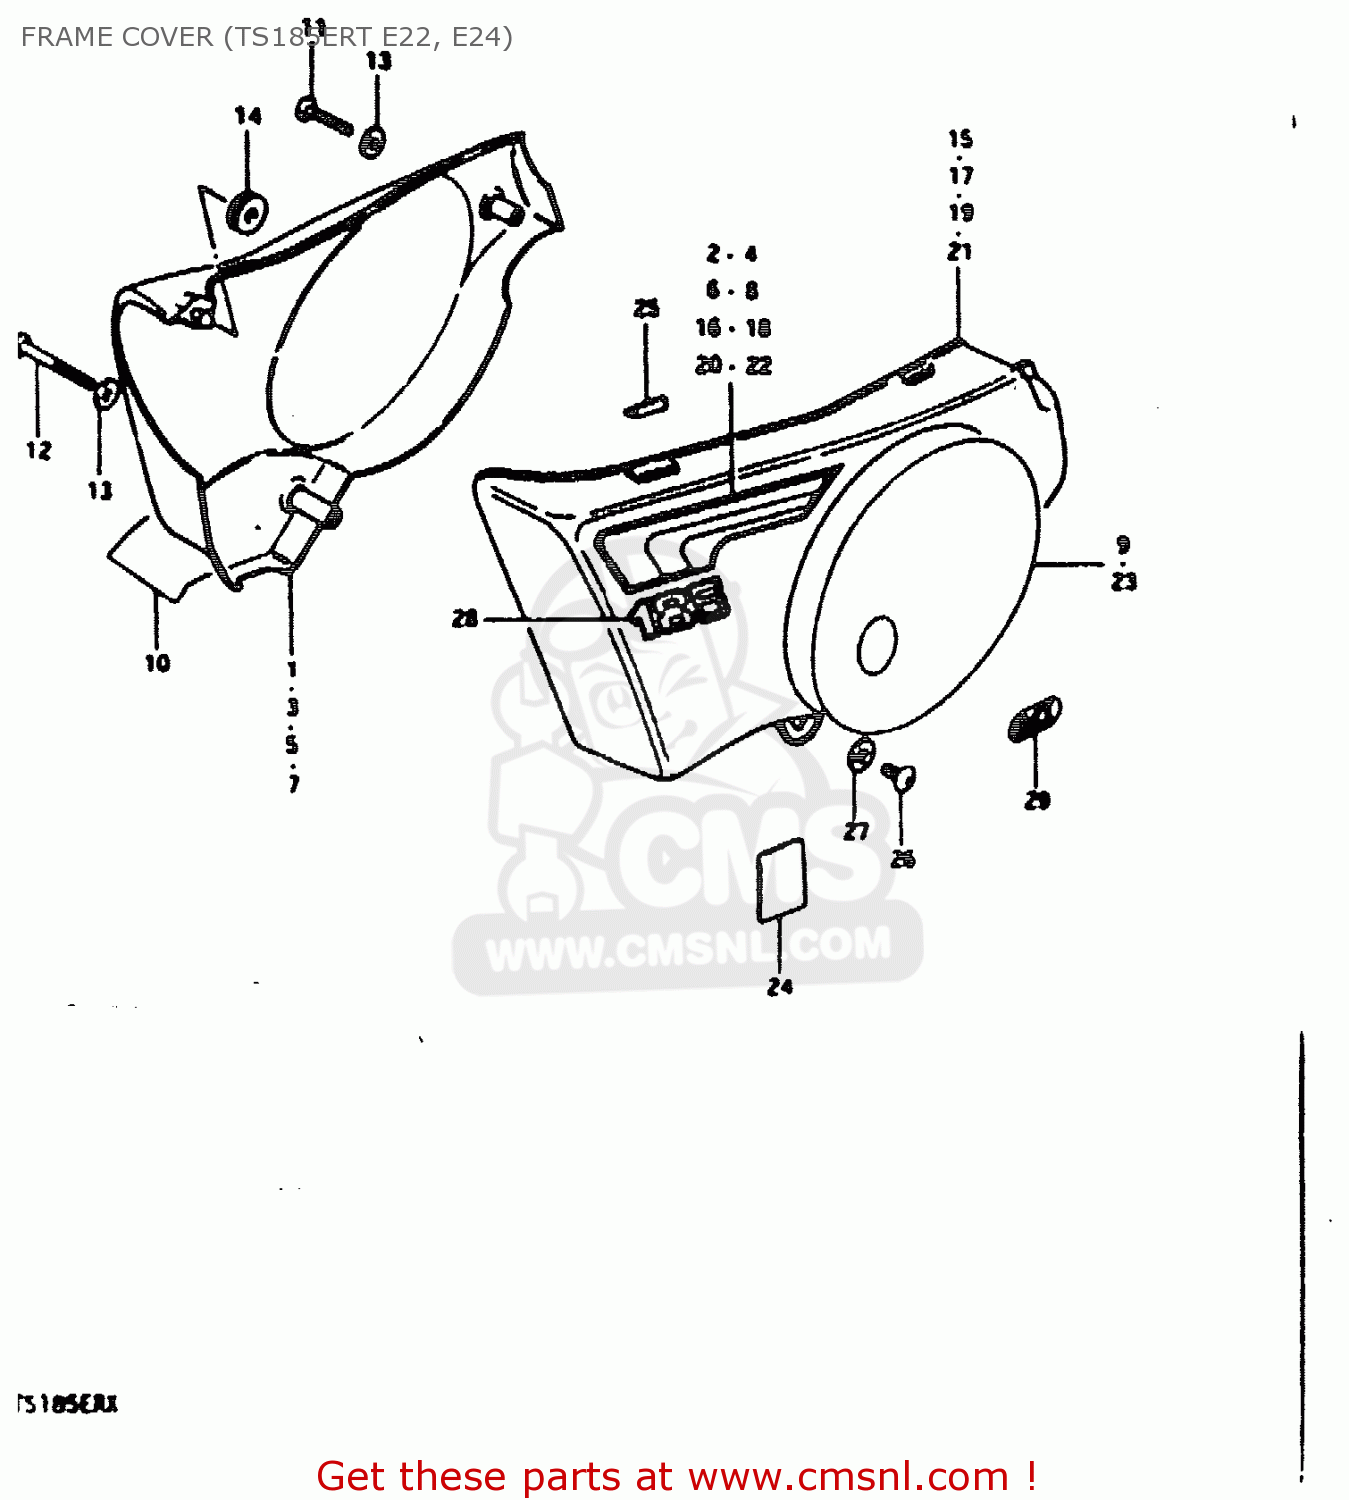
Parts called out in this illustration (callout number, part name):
1	COVER, FRAME RH (BLUE)
2	TAPE, RH
3	COVER, FRAME RH (YELLOW)
4	TAPE, RH
5	COVER, FRAME RH (RED)
6	TAPE, RH
7	COVER, FRAME RH (WHITE)
8	TAPE, RH
9	EMBLEM, NO.1 RH
10	EMBLEM,FRAME COVER,RIGHT
11	SCREW
12	SCREW
13	WASHER (8.7X22X2)
14	CUSHION
15	COVER, FRAME LH (BLUE)
16	TAPE, LH
17	COVER, FRAME LH (YELLOW)
18	TAPE, LH
19	COVER, FRAME LH
20	TAPE, LH
21	COVER, FRAME LH (WHITE)
22	TAPE, LH
23	EMBLEM, LH
24	PROTECTOR(170X95X3.0)
25	CUSHION,FRAME COVER
26	SCREW 6X12
27	WASHER
28	EMBLEM "185"
29	EMBLEM,CCIS
